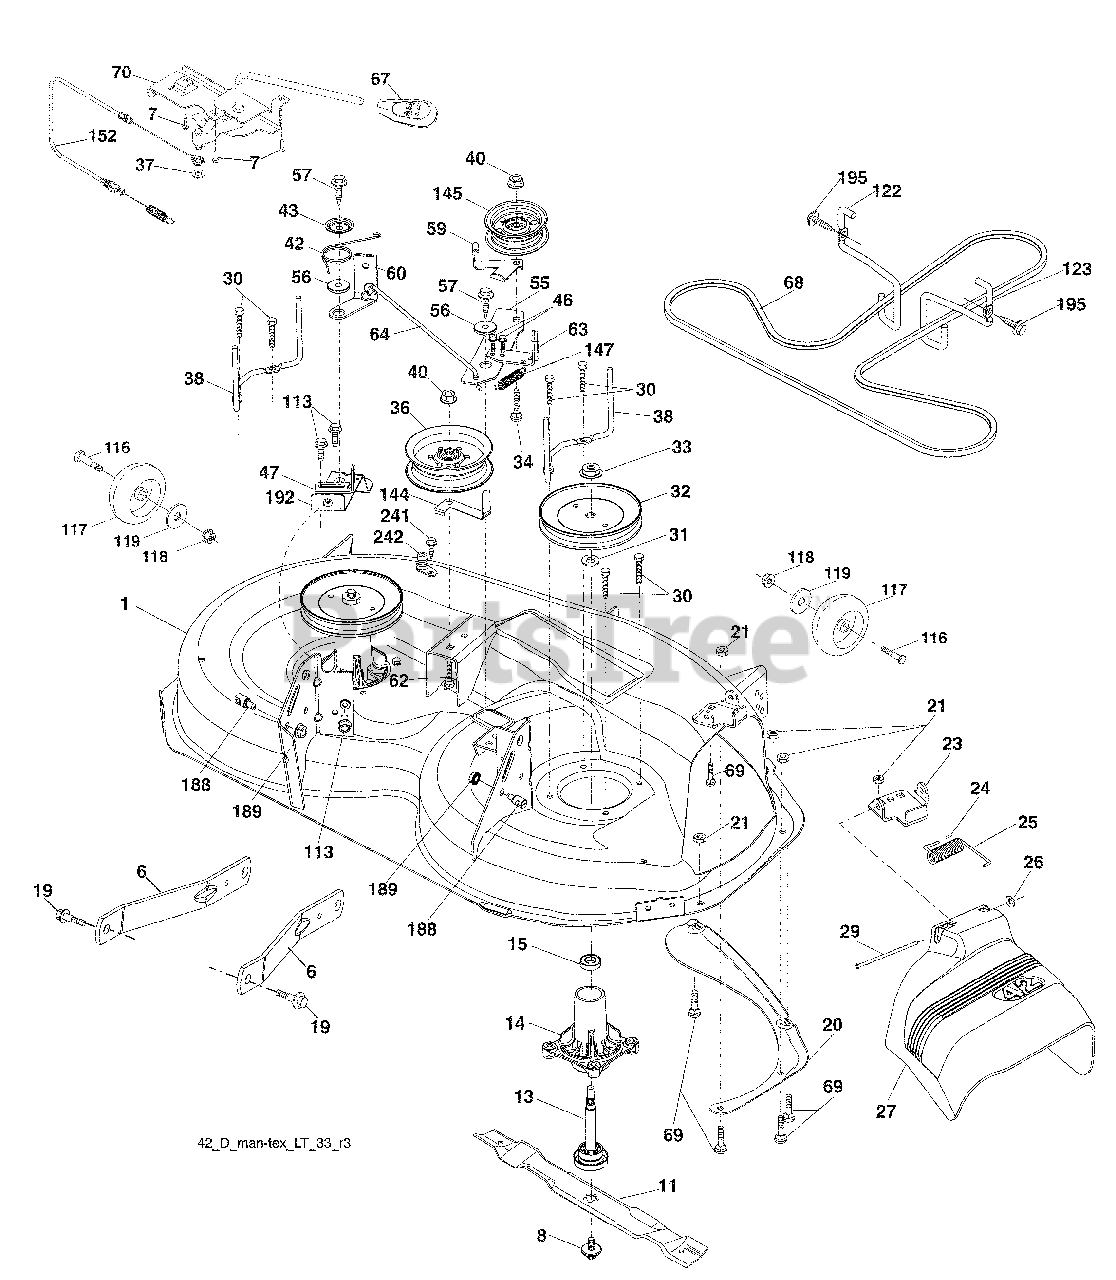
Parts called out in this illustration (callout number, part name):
1	Mower Housing
6	Arm Suspension
7	Screw #10 x .750 BOS Thread
8	Bolt/Washer Asm 7/16-20 unf
11	Blade, 42" Hi-Lift
13	Shaft Assembly, Mandrel
14	Housing, Mandrel
15	Bearing, Ball, Mandrel
19	Bolt, Shoulder
20	Baffle, Vortex
21	Nut, Crownlock 5/16-18 unc
23	Bracket, Deflector
24	Cap, Sleeve
25	Spring, Torsion, Deflector
27	Shield, Deflector
29	Rod, Hinge
30	Screw Thdrol Rolling Wsh Hd
31	Washer, Spacer
32	Pulley, Mandrel
33	Nut, Toplock, Flanged
34	Bolt Carr Sh. 3/8-16 x 1-1/2 Gr. 5
36	Pulley, Idler, Flat
37	Washer
38	Keeper Belt LH Mandrel
40	Nut, Lock Flg. 3/8-16 unc
42	Spring Torsion Brake
43	Spring Torsion Retainer
46	Screw Thd Roll 1/4-20 x 5/8
47	Bracket Clutch Cable
55	Arm, Idler
56	Spacer, Retainer
57	Screw 3/8-16 x 1
59	Guard, Tuv Idler
60	Arm Brake Mower
62	Bolt Rd Hd Sq Nk 3/8-16 unc x
63	Arm Brake Mower
64	Link Brake
67	Handle Clutch Cable
68	V-Belt
69	Bolt
70	Clutch Asm Manual
113	Screw 5/16-18
116	Bolt, Shoulder
117	Wheel, Gauge
118	Nut, Crownlock 3/8-1
119	Washer 13/32 x 7/8 x 14 Ga.
122	Keeper Belt Engine LH
123	Keeper Belt Engine RH
144	Keeper Belt
145	Pulley Idler
147	Spring Return
152	Manual Clutch Cable
188	Stud Fastener
189	Nut Lock Hex Flange
192	Bracket Brake Stand LH
195	Screw 3/8-16 x 3/4
241	Screw TT #10-32 5 3/8 Flange
242	Port Washout
